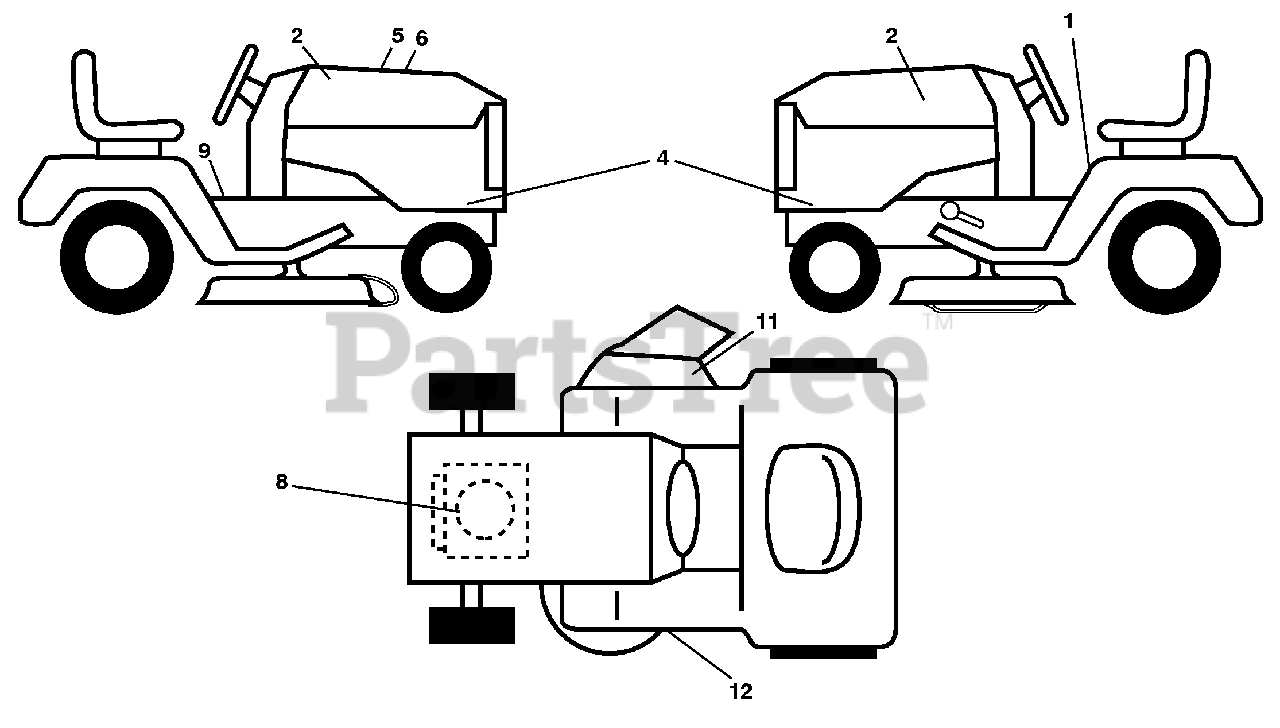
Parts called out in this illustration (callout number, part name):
1	Decal, Fender Warn./Instructions
2	Decal, Hood Logo
4	Decal, Hood Panel
5	Decal, Customer Respons.
6	Decal, Replacement
8	Decal, Engine
9	Decal, Battery Dnge/Poi
11	Decal, Warning
12	Decal, Mower V-Belt Schematic
